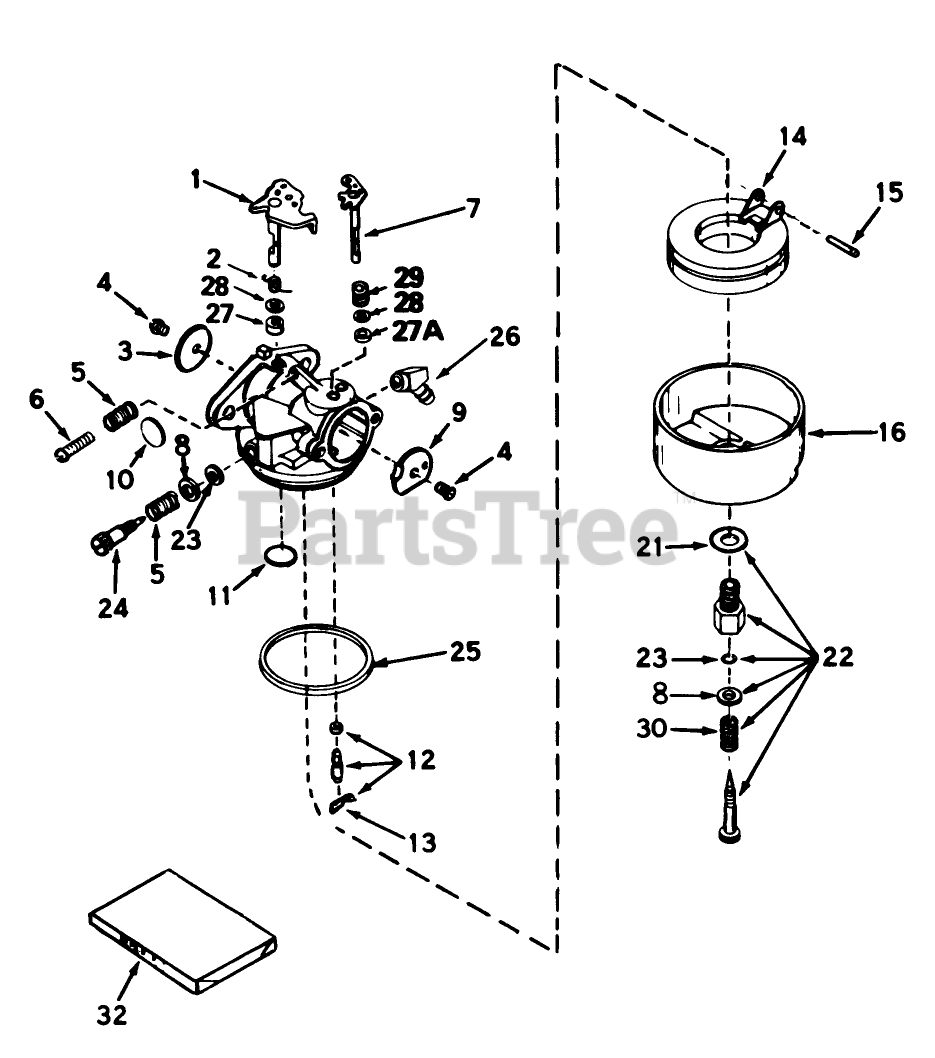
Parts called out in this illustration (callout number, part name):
1	Shaft/Lever-Throttle
2	Spring-Return, Throttle
3	Shutter-Throttle
4	Screw-Shutter
5	Spring-Tension
6	Screw-Throttle Crack Screw / Idle Speed
7	Shaft Lever Assy., Choke
8	Washer
9	Shutter, Choke
10	Plug-Welch, Idle Mixture Well
11	Plug-Welch, Atmospheric Vent
12	Inlet Needle, Seat Clip Assy. (Incl. No. 13)
13	Clip-Spring
14	Float
15	Shaft-Float
16	Bowl-Float (no drain)
21	Washer-Bowl Nut
22	Adjustment Screw Assy., Main (Incl. Ref.#8,21,2330)
23	ORing
24	Screw, Idle Adj.
25	O Ring-Bowl, Float
26	Fitting-Inlet, Fuel
27	Seal-Dust
27A	Seal-Dust
28	Washer-Seal, Dust
29	Spring-Choke
30	Spring
32	Repair Kit
